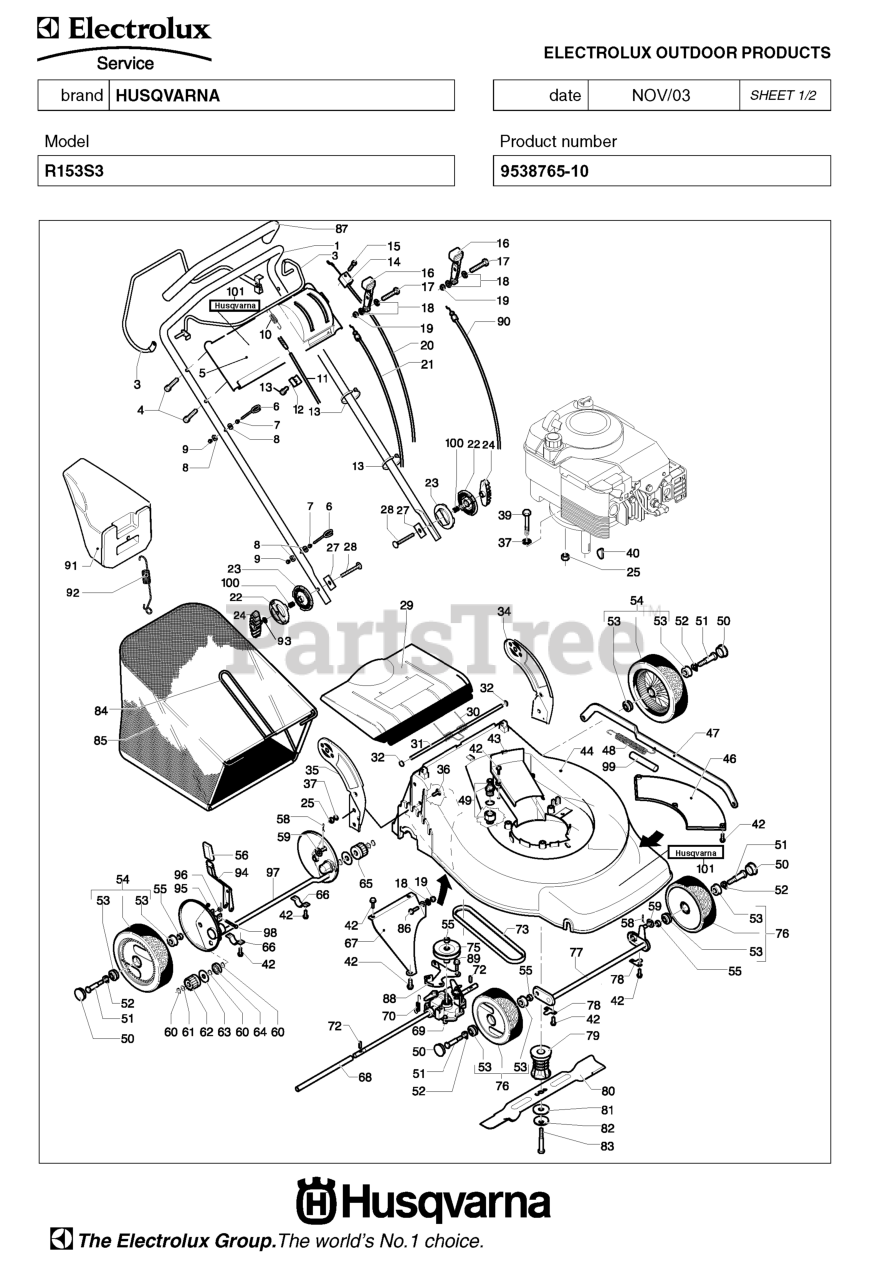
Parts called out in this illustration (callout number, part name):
42	Screws
58	Pins
60	Washers
